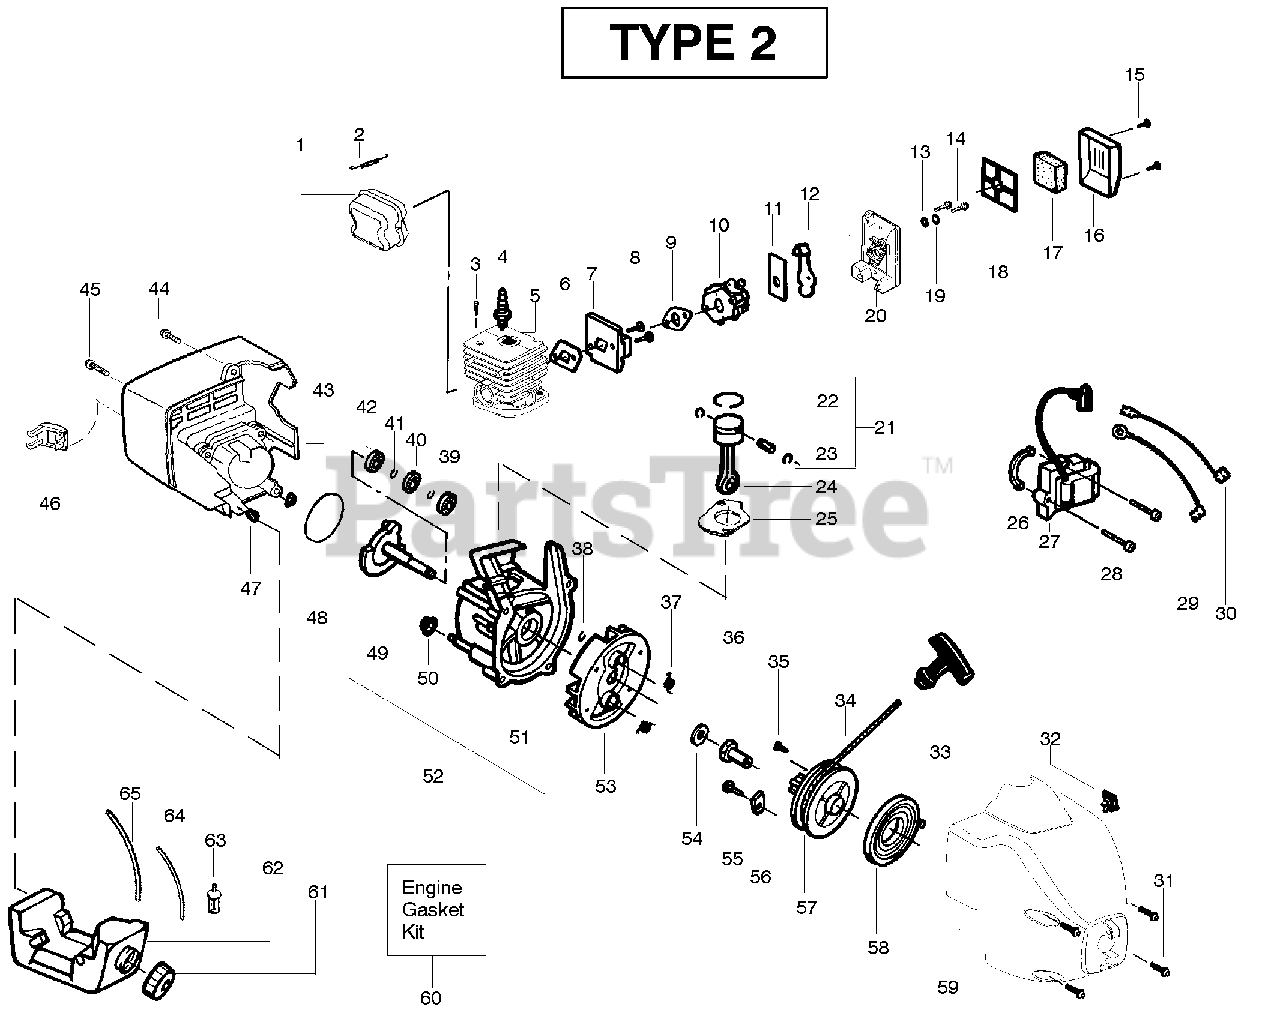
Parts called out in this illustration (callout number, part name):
1	Kit - Muffler
2	Muffler Spring
3	Screw-Cylinder
4	Spark Plug (RCJ 6Y)
5	Kit - Cylinder
6	Gasket-Cyl/Carb.(kit)
7	Adaptor-carb.
9	Gasket-Carb.(kit)
10	Kit-Carb. (WA226)
11	Plate-Choke Mounting
12	Lever-Choke
16	Cover-Air Box
17	Foam-Air Filter
18	Plate-Air Filter Support
19	Spacer-Choke
21	Kit - Piston
22	Piston Ring
23	Retainer-Piston Pin
24	Assy-Connecting Rod
25	Gasket-Cylinder(kit)
26	Spacer-Module
27	Ignition Module
29	Assy-Ground Wire
30	Assy-Leadwire
31	Screw
32	Kit-Switch
33	Handle-Starter
34	Kit - Rope
36	Coupling-Drive
37	Spring-Starter Dog
38	Retain. Ring-C'shaft
39	Bearing-Outer
40	Seal-C'case
41	Retainer Ring-C'case
42	Bearing-Inner
45	Screw
46	Guard-Muffler
47	Isolator-Shroud
48	O-Ring-C'case(kit)
49	Assy-Crankshaft
50	Isolator-Crankcase
51	Assy-Crankcase
52	Assy-C'case & C'shaft
53	Assy-Flywheel
54	Washer-Flat
56	Retainer-Can
57	Kit-Starter Pulley
58	Spring-Starter
59	Assy-Fan Housing
60	Kit-Engine Gasket
61	Assy-Fuel Cap
62	Assy-Fuel Tank
63	Assy-Fuel Pickup
64	Kit-Fuel Line
65	Kit-Fuel Line
